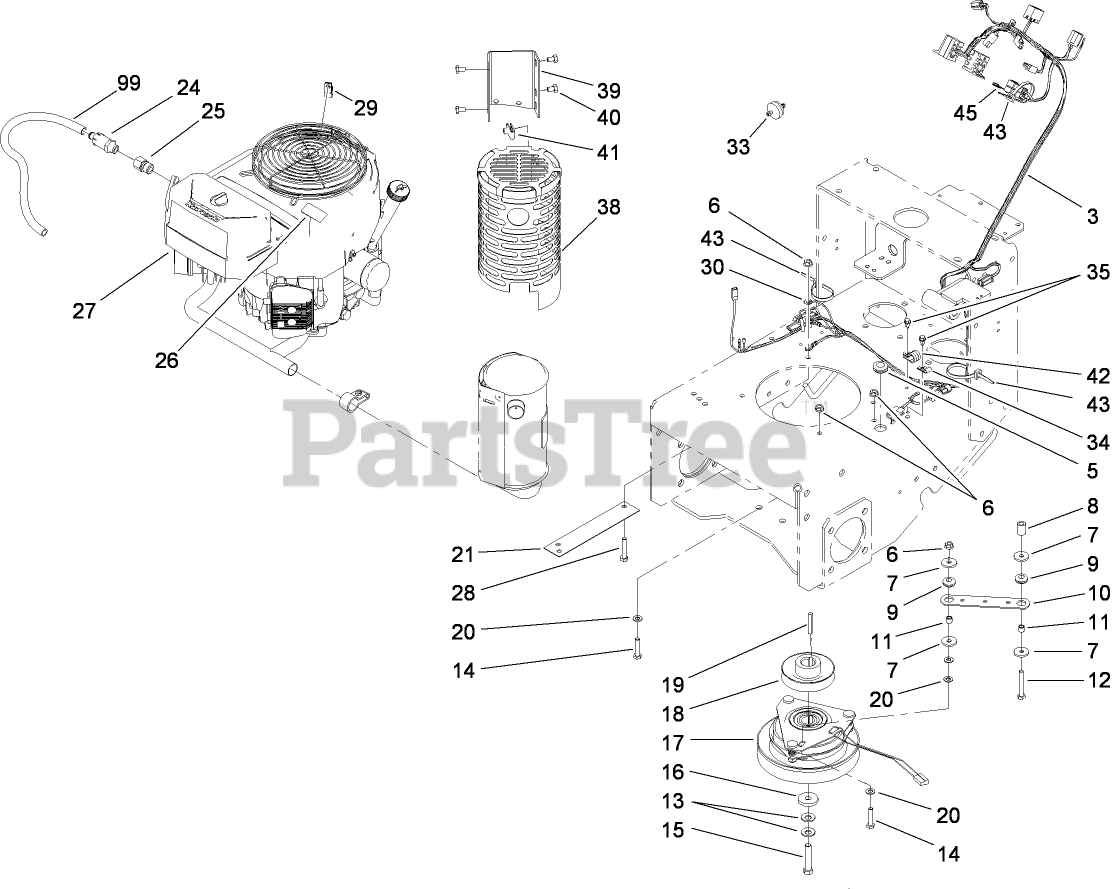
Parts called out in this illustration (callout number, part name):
3	HARNESS-WIRE
5	GROMMET
6	NUT-HF
7	WASHER
8	TUBE-RETAINER
9	GROMMET
10	STRAP-CLUTCH, BRAKE
11	SPACER
12	SCREW-HH
13	WASHER-SPRING
14	SCREW-HH
15	SCREW-HH
16	WASHER
17	CLUTCH / BRAKE ASM
18	Pulley
19	KEY-SQUARE
20	WASHER-PLAIN
21	COVER-PULLEY
24	VALVE-DRAIN, OIL
25	Adapter
26	DECAL-WARNING
28	SCREW-HH
29	CLAMP-CABLE
30	WASHER-LOCK
33	FILTER-FUEL
34	CLIP-CLOSED, INSULATED
35	SCREW
38	MUFFLER GUARD ASM
39	BRACKET-GUARD, MUFFLER
40	SCREW-HH
41	NUT-U
42	CLAMP-R
43	TIE-CABLE
45	FUSE-BLADE, 10 AMP
99	HOSE-DRAIN, OIL
